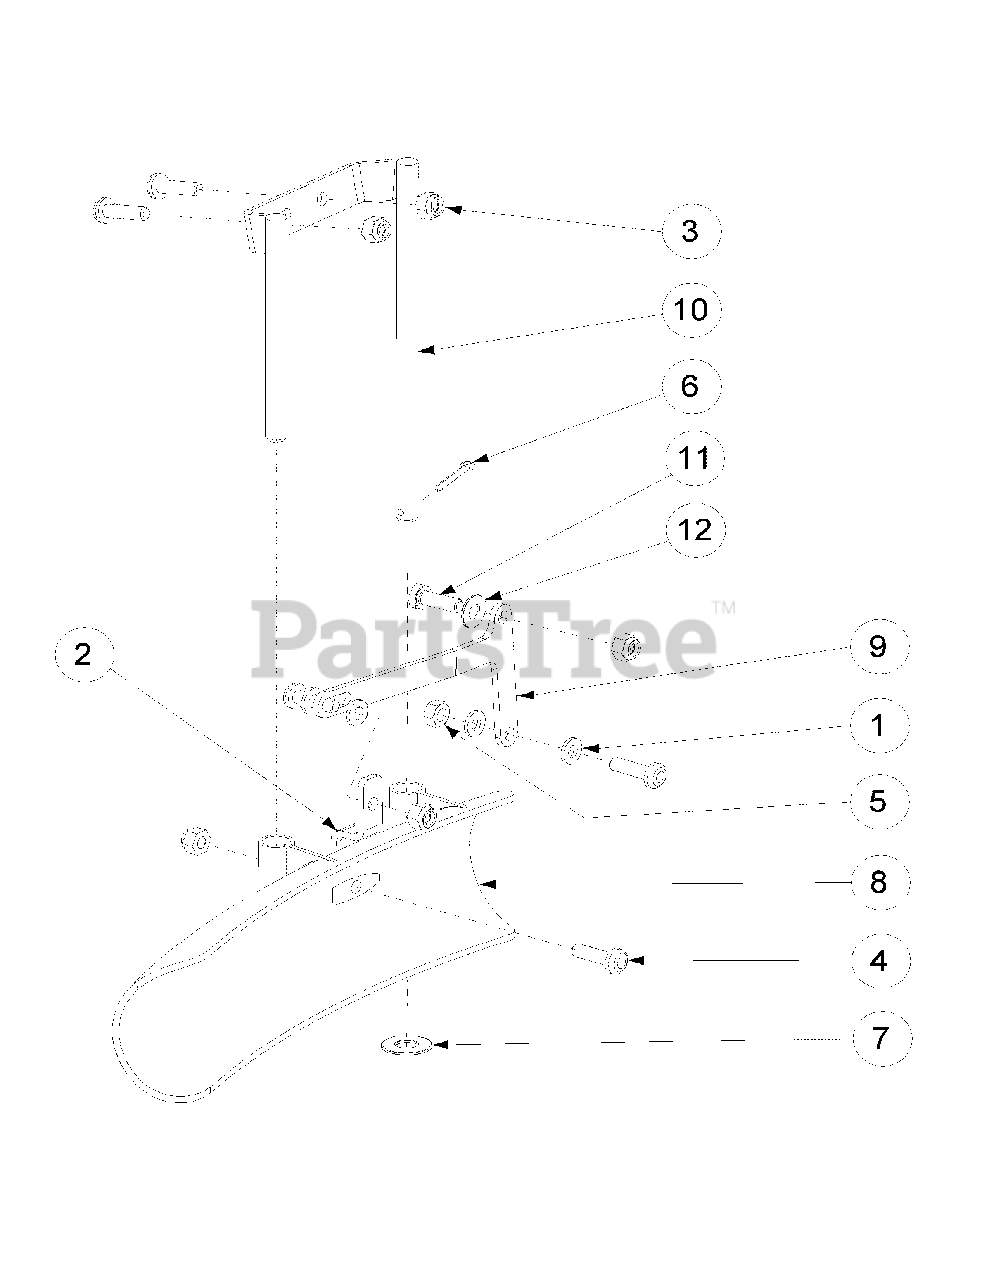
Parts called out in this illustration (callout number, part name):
1	Flat Washer, 1/4 Nylon
2	Offset Deflector Bracket
3	Nylock Nut, 1/4-20
4	1/4 -20 x 7/8 Pan Head Mach Screw
5	Hex Nut, 1/4-20
6	Cotter Pin, 1/8 x 1
7	Flat Washer, 3/8
8	Deflector Tube, Plastic Only
9	Deflector Mount Lever
10	Deflector Mount Weldment
11	HHCS: 1/4-20 x .75
12	Flat Washer, 1/4" SS
